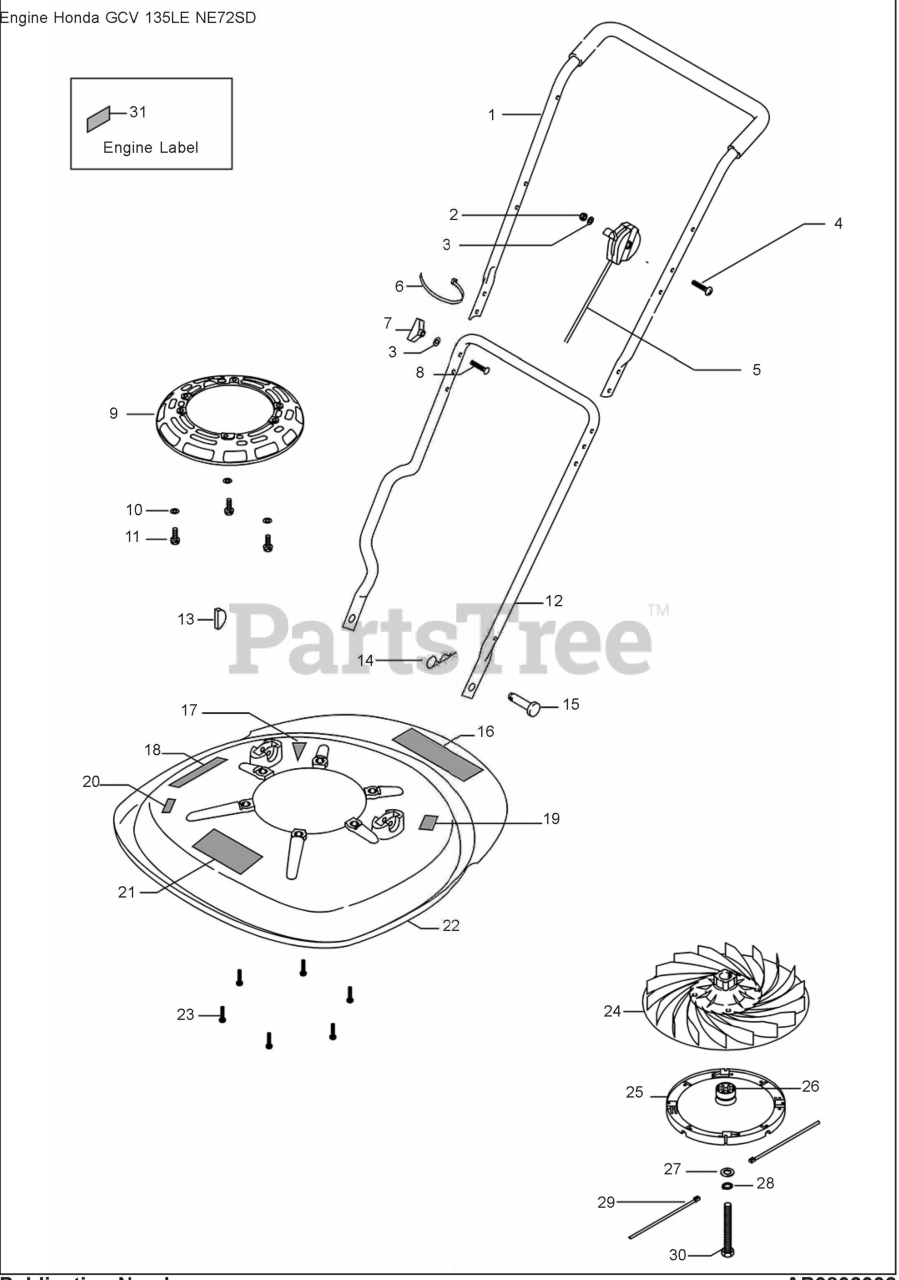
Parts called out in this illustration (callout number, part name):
1	HANDLE UPPER ASSEMBLY
2	NUT M6 NYLOC GME/D
3	WASHER 6.4-6.7 IDX12.1-12.3
4	SCREW M6 X 55
5	CABLE CHOKE PETROL HOVER
6	TIE WRAP (3.5 X 150)
7	PLASTIC WING NUT M6 ORANGE
8	BOLT M6 X 50 SQUARE CUP
9	ADAPTOR PLATE SAE ENGINE MOU
10	M10 WASHER
11	SOCKET CAP SCREW 3/8X16 UNCT
12	HANDLE LOWER(PET HOVER)
13	KEY(WOODRUFF)
14	SPRING CLIP SMALL
16	LABEL WARNING
17	LABEL PETROL SPILLAGE
18	LABEL STEP HERE WHEN STARTING
19	LABEL HOT MUFFLER
20	LABEL FINGER WARNING
21	LABEL HUSQVARNA HVT52
22	HOOD HVT52
23	SCREW HEX FLANGE HEAD 10UNC
24	IMPELLER HVT52
25	GCT DISC 21
26	DISC SPACER-HVT (SHORT)
27	WASHER I/D 0.390 X O/D 3/4 I
28	WASHER-SPRING
29	CUTTER LINE YELLOW (QTY 100)
30	BOLT 3/8 UNF X 4" PATCHLOC
31	LABEL MOWER PETROL SPILLAGE
